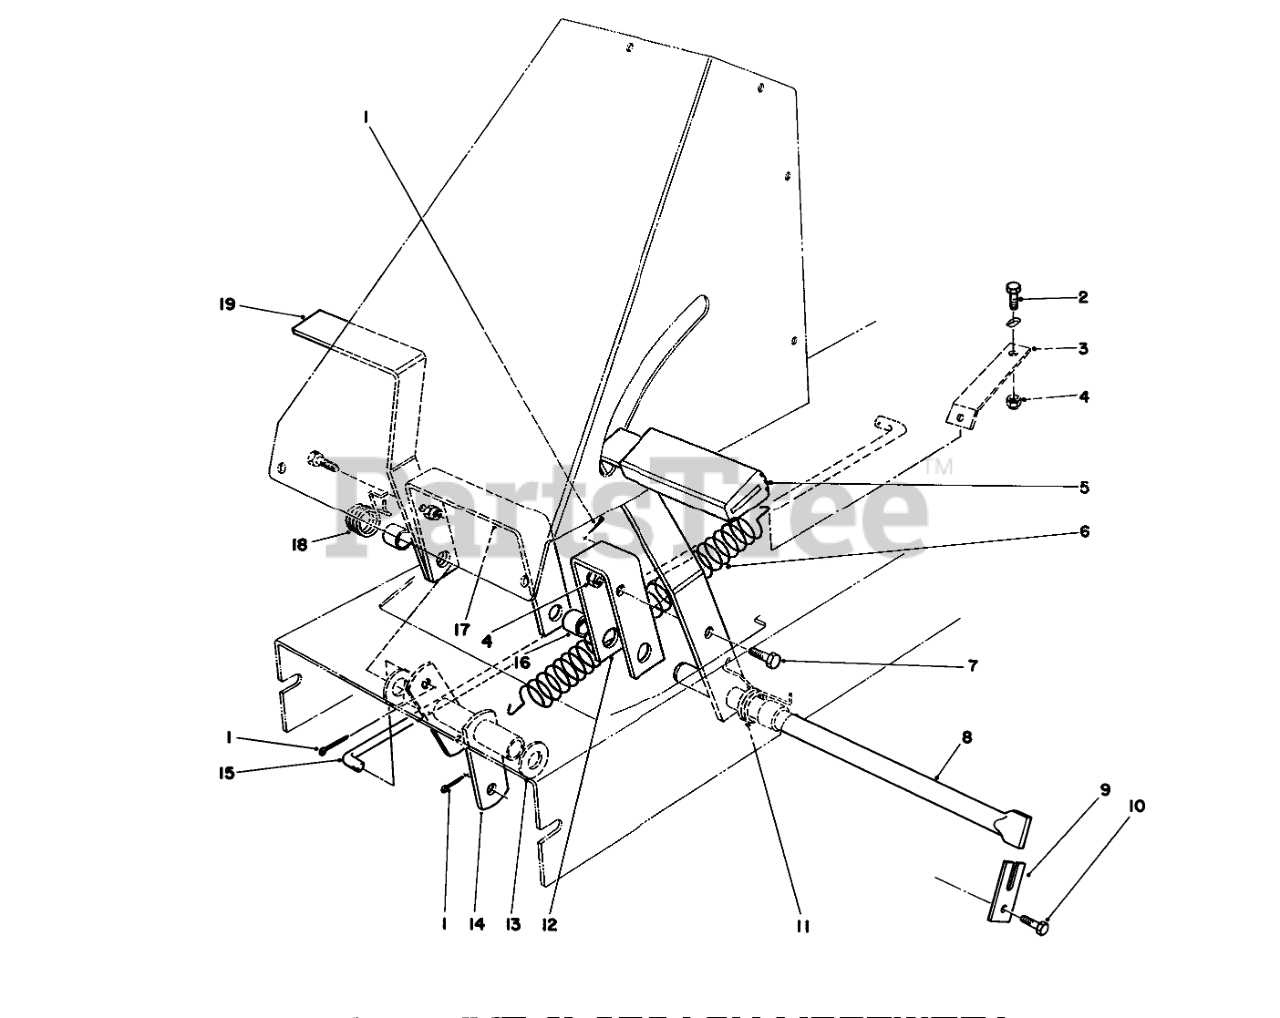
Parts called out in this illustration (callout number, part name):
1	PIN-COTTER
2	SCREW-HH
3	BRKT-SPRING RET
4	NUT-LOCK, NI
5	PAD-PEDAL
6	SPRING-EXTENSION
7	SCREW-HH
8	SHAFT-PEDAL PIVOT
9	RETAINER-SHAFT
10	SCREW-HH
11	SPRING-TORS CLUTCH
12	Bracket-Clutch Pedal
13	WASHER-FLAT
14	Pivot Tube
15	ROD-ENGAGE
16	SPACER-PEDAL
17	Bracket-Brake Pedal
18	SPRING-TORS BRAKE
19	Pedal
